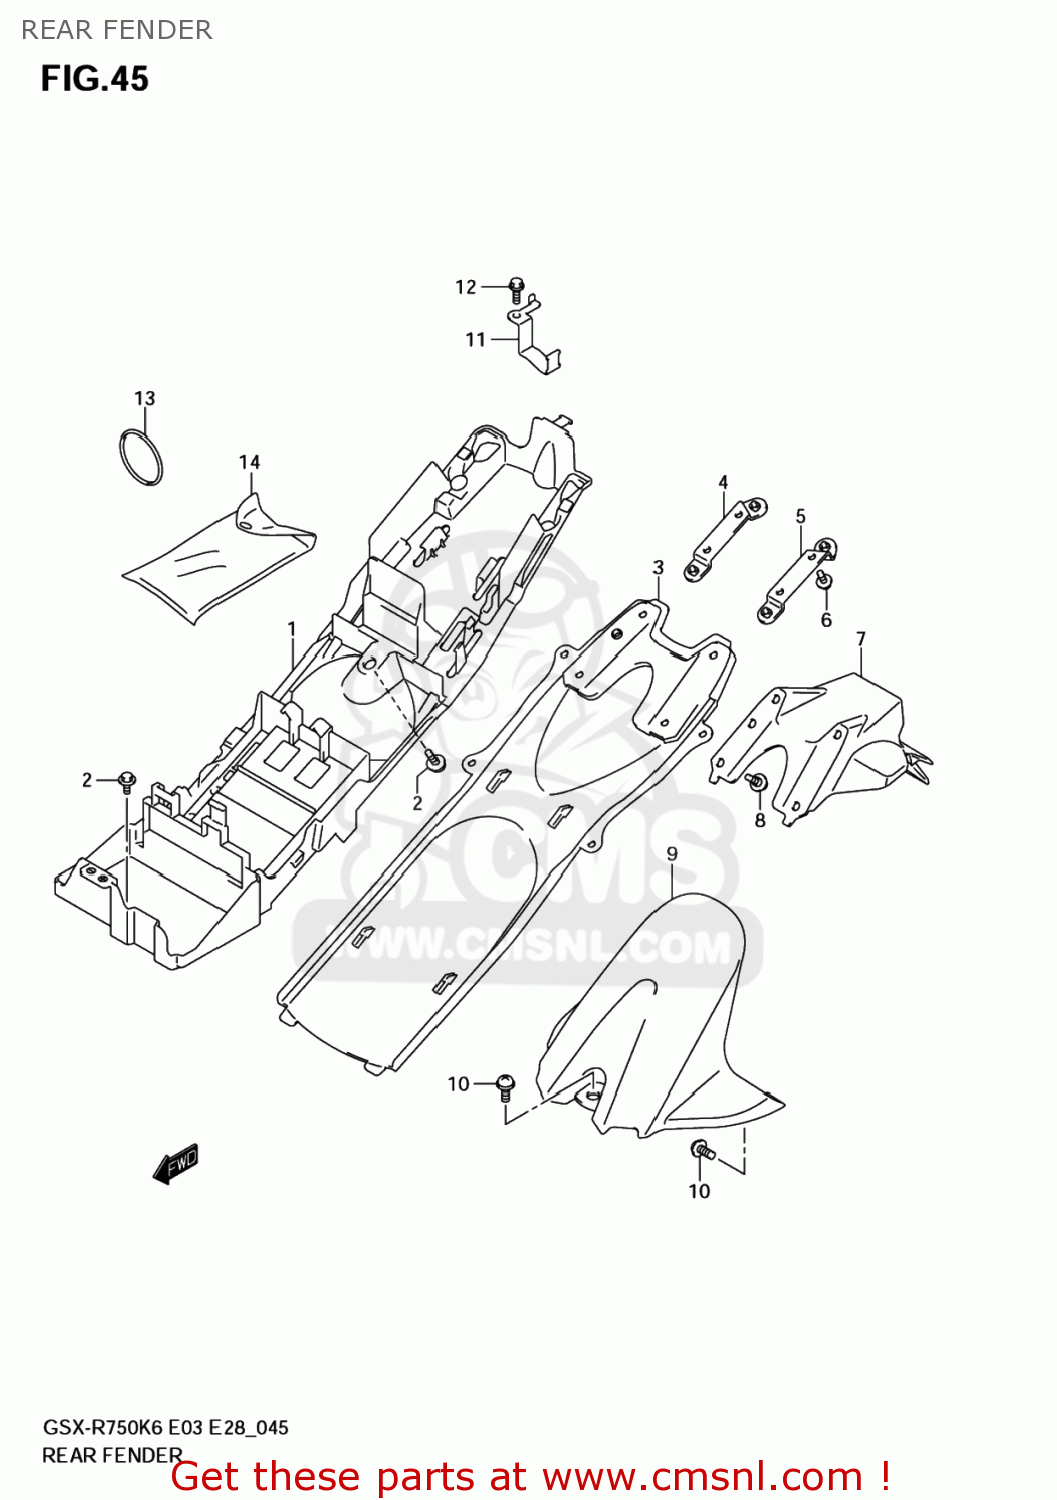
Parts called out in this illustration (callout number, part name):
1	FENDER,RR FR
2	BOLT
3	COVER,RR FENDER FR
4	BRACKET,RR FENDER,R
5	BRACKET,RR FENDER,L
6	BOLT
7	FENDER,RR RR
8	BOLT (6X16)
9	FENDER,REAR LO
10	BOLT(6X14)
11	PLATE,FUSE BOX
12	BOLT
13	O RING(D:3.5,ID:61)
14	TOOL ASSY
